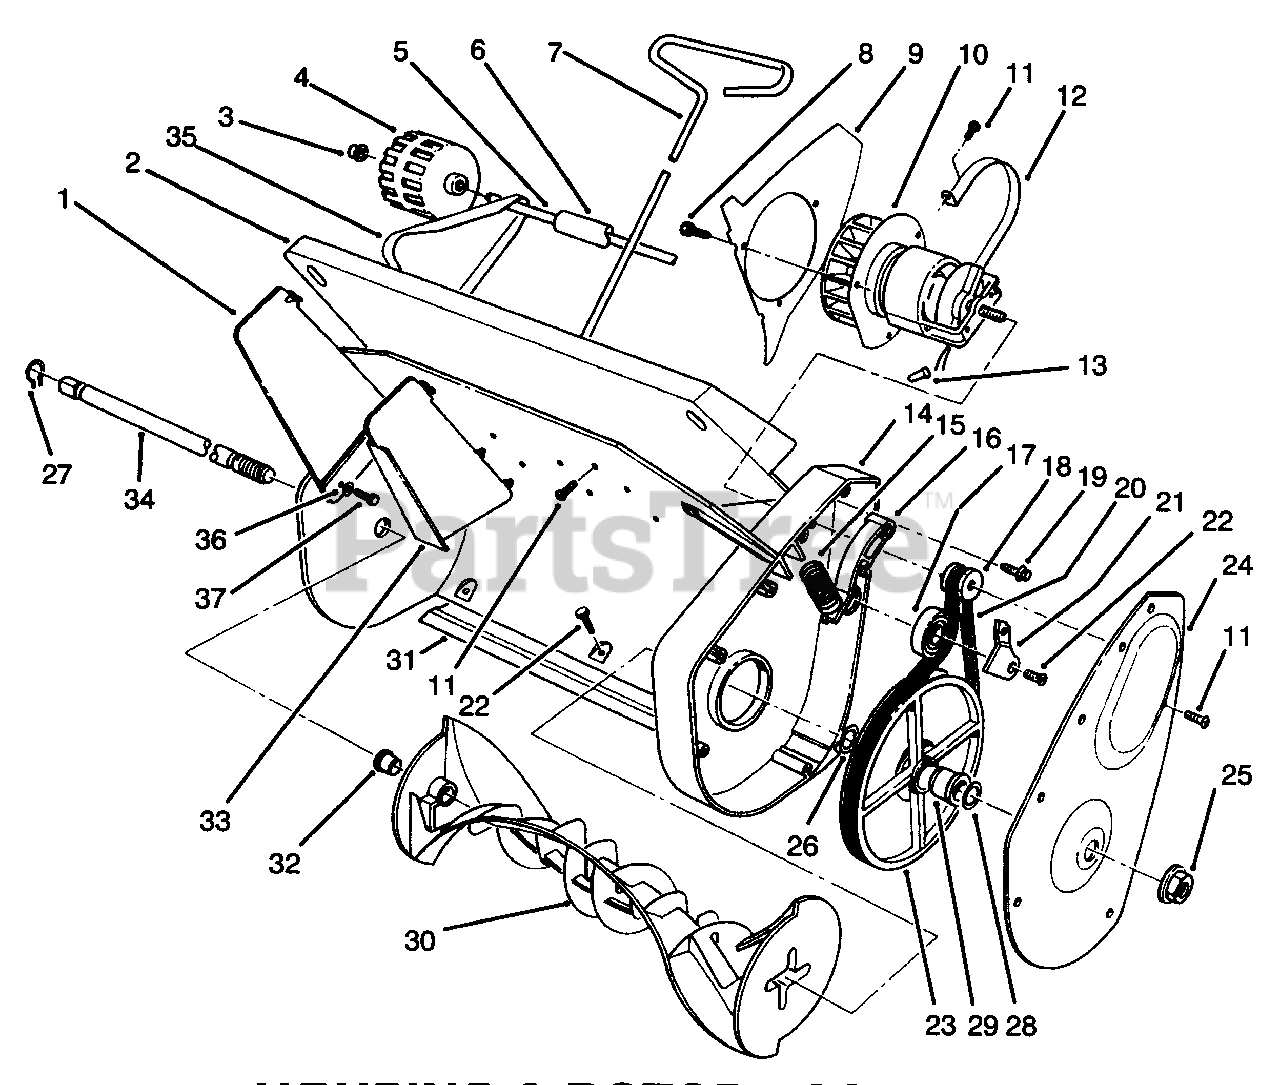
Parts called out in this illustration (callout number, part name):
1	Vane-Outer
2	Mount-Vane
3	Nut-Push On
5	Shaft-Axle
6	Sleeve-Axle
7	Rod-Vane Adjustment
8	Screw-Self Tapping
9	Baffle-Air
11	Screw-Self Tap. Pan Hd.
12	Mount-Motor
13	Connector-Wire
15	Spring-Compression Idler
16	Arm-Idler
17	Bearing-Ball
18	Pulley-Drive
19	Screw-Hex. Washer Hd.
20	Belt-Drive
21	Retainer-Idler Pulley
22	Screw-Self Tap. Pan Hd.
23	Pulley-Driven
24	Cover-Belt Case
25	Nut-Flange Lock
26	Washer-Thrust
27	Ring-Retaining
28	Washer-Thrust
29	Bushing-Rotor
32	Bushing-Rotor
33	Vane-Center
34	Shaft-Rotor
35	Bracket-Wheel R.H.
37	Screw-Self Tapping
